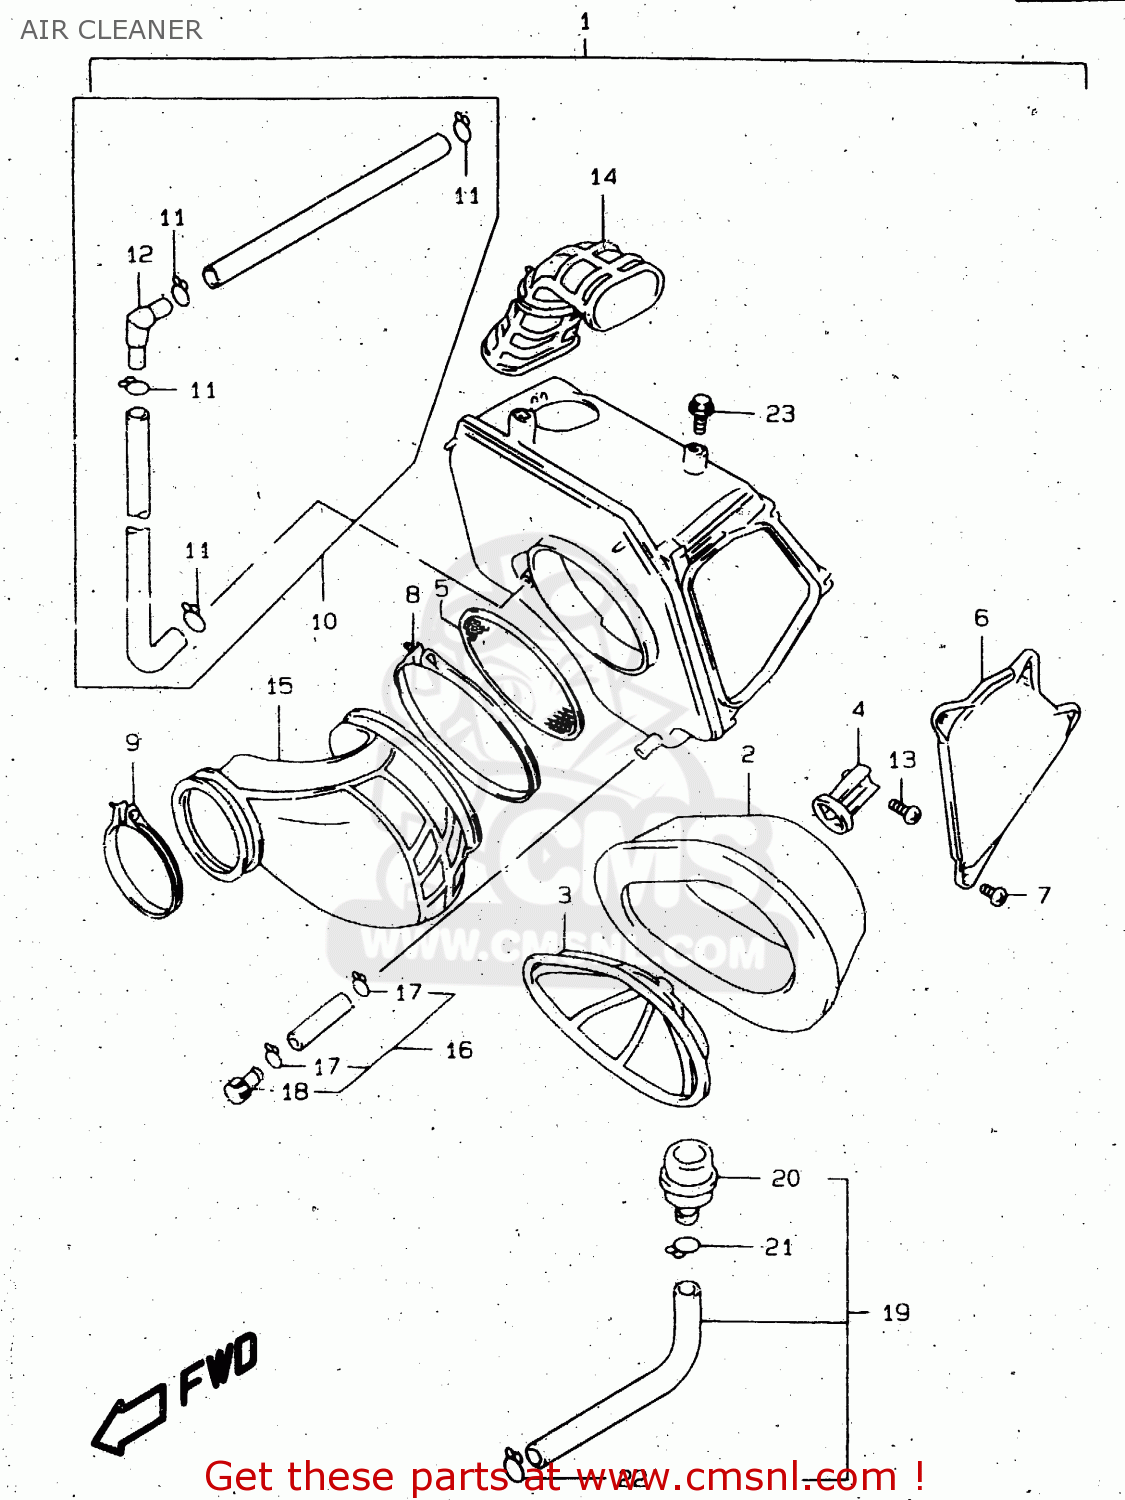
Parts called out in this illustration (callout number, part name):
1	CLEANER ASSY,AIR
2	FILTER
3	HOLDER,FILTER
4	STOPPER,HOLDER
5	TRAP,FRAME
6	CAP,CLEANER
7	SCREW 5X12
8	CLAMP,OUTLET TUBE
9	CLAMP
10	TUBE ASSY,BREATHER
11	CLIP
12	JOINT
13	SCREW
14	TUBE,INLET
15	TUBE,OUTLET
16	TUBE ASSY,DRAIN
17	CLIP
18	PLUG
19	CLEANER ASSY,AIR NO.2
20	FILTER,2ND AIR CLEANER
21	CLIP
22	CLIP
23	BOLT
